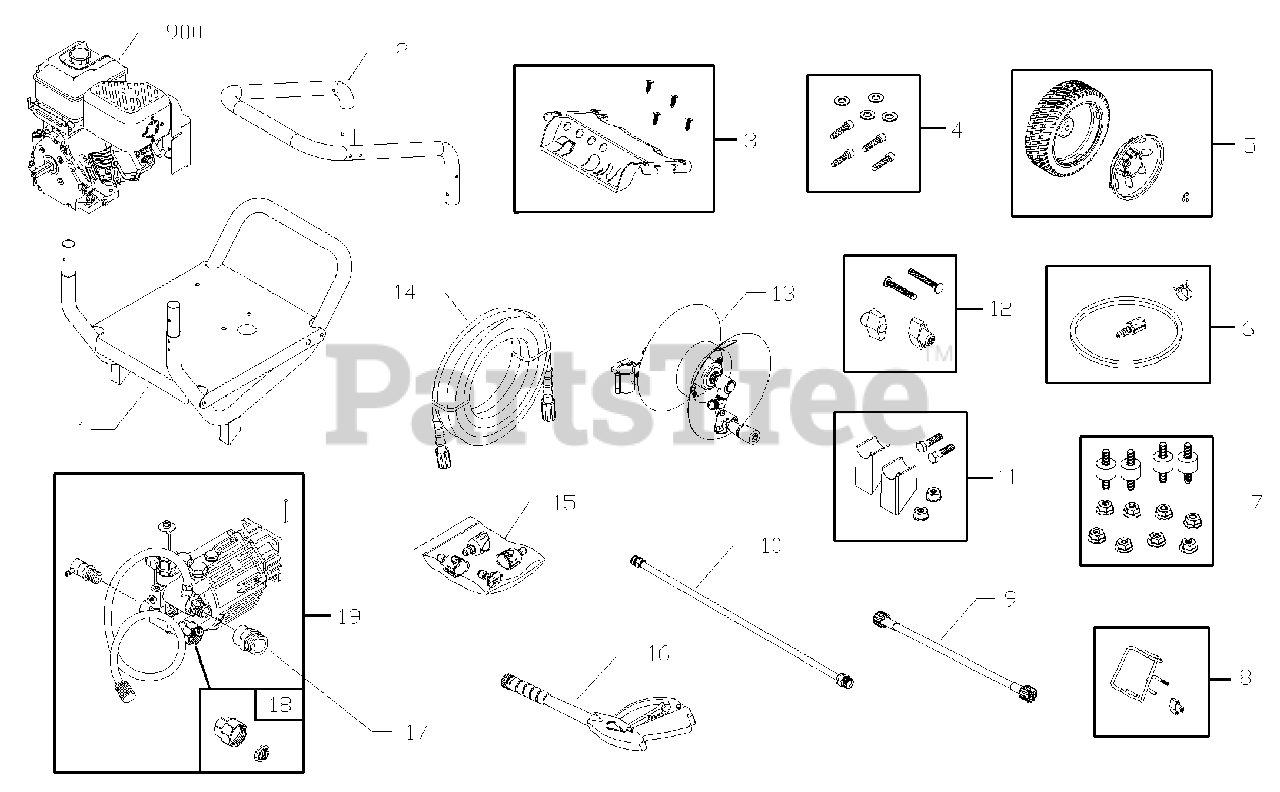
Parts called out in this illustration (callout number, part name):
4	KIT, Hardware, Pump Mounting
6	KIT, Chemical Hose and Filter
7	KIT, Vibration Mount
10	EXTENSION, QC
11	KIT, Vibration Mount
12	KIT, Hardware, Handle
15	KIT, QC Nozzles
16	GUN
18	CONNECTOR, Garden Hose
900	*ENGINE
